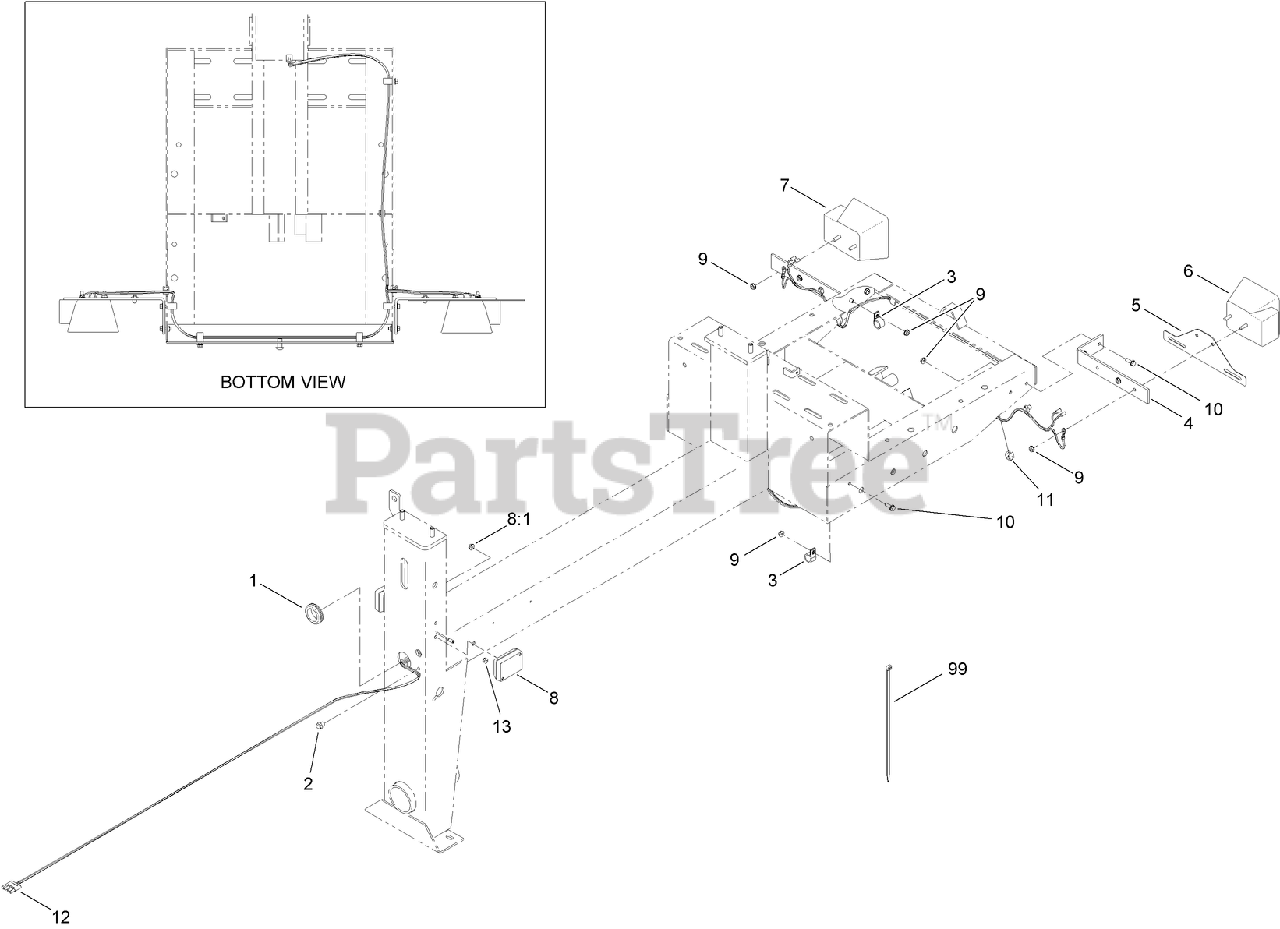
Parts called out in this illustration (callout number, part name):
1	GROMMET
2	CLIP-TIE
3	CLAMP-CABLE
4	BRACKET-UNIVERSAL
5	HOLDER-PLATE, LICENSE
6	LIGHT-TAIL, LH
7	LIGHT-TAIL, RH
8	LAMP-MARKER, FRONT SIDE
8:1	NUT-KEPS
9	NUT-KEPS
10	SCREW-HHF
11	CLIP-EDGE
12	HARNESS-WIRE
13	GROMMET
99	TIE-CABLE
